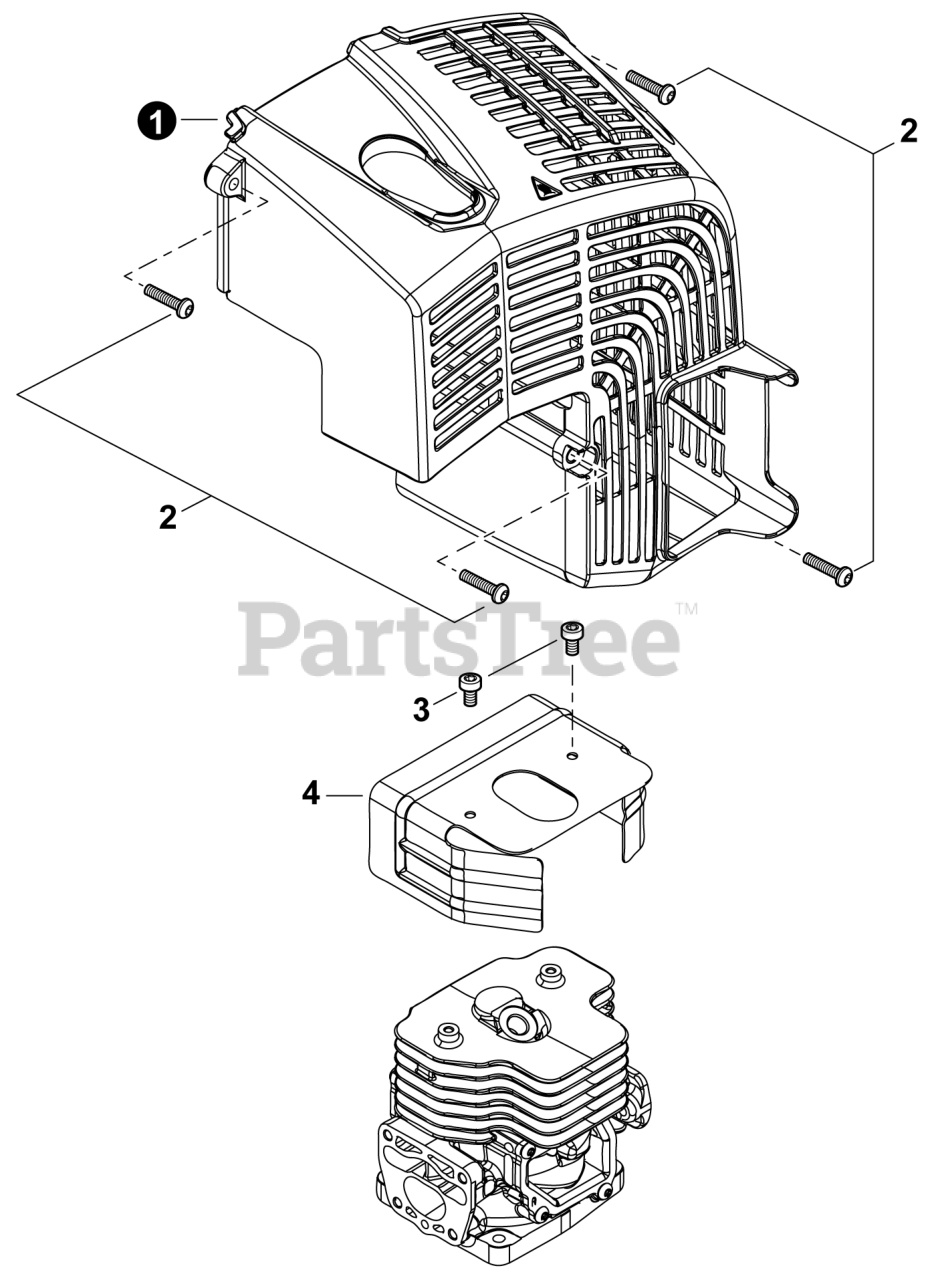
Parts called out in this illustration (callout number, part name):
1	COVER, ENGINE
2	BOLT, TORX 5x20
3	BOLT, TORX 4x8
4	COVER, CYLINDER
